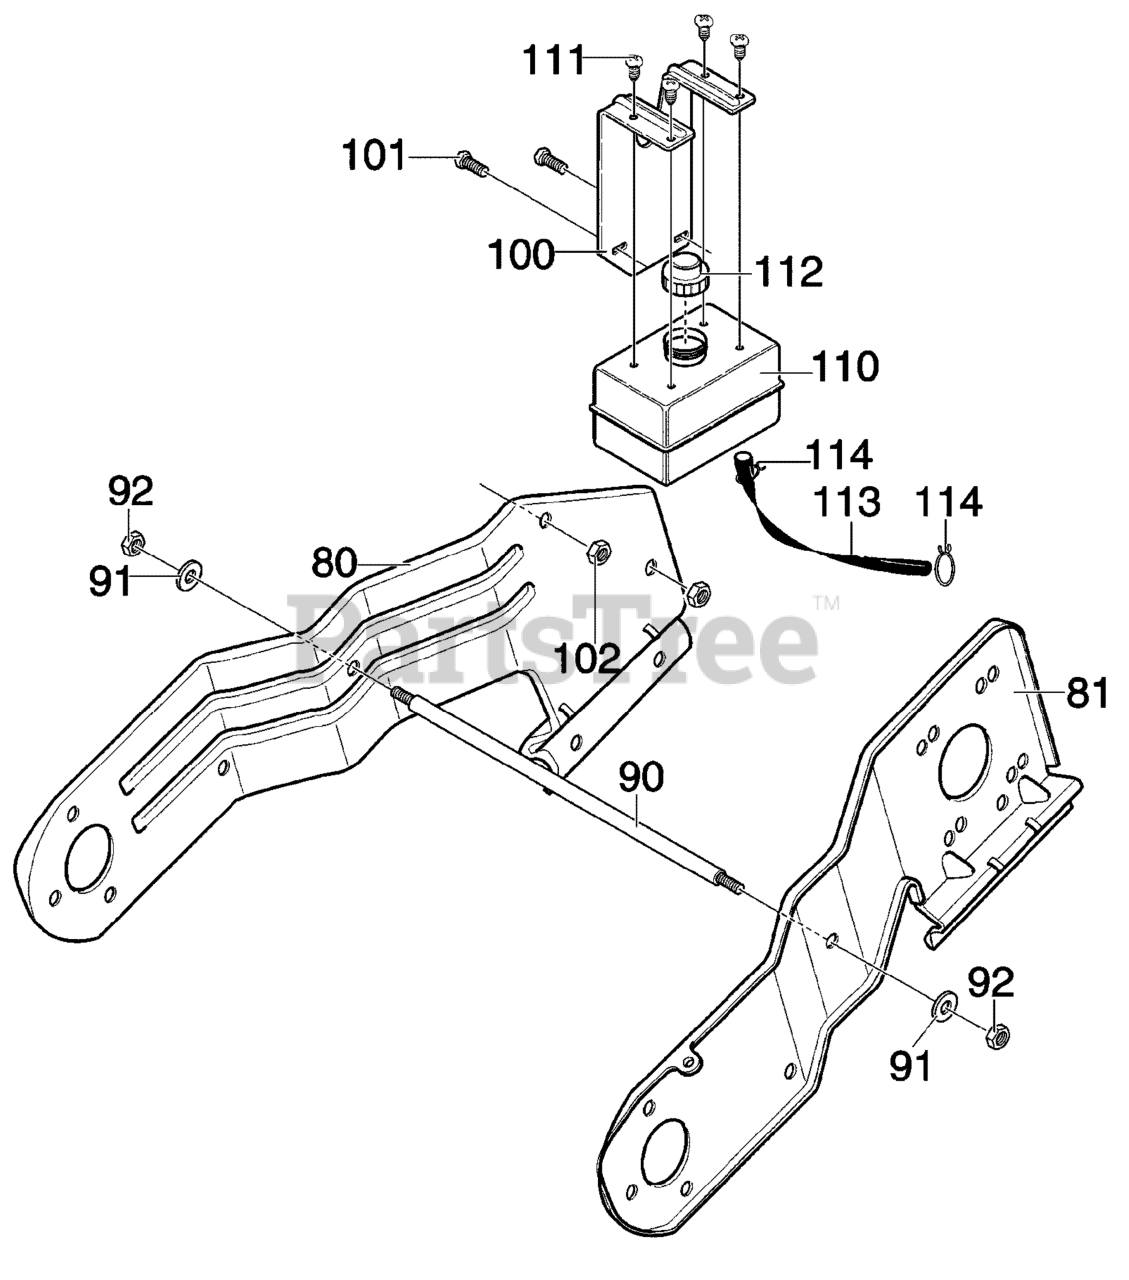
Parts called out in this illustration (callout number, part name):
80	FRAME SIDE SUPPORT RH
81	FRAME SIDE SUPPORT LH
90	ROD, SUPPORT
91	WASHER, HVSPTLK
92	NUT, 3/8-16 REGHEX
100	BRACKET, GAS TANK
101	SCREW, 1/4-20X.75
102	NUT, 1/4-20 YZ
110	TANK, FUEL
111	SCREW, 1/4-14X.88 WAHHTAP
112	CAP, GAS-BLACK
113	TUBING 11.50 IN.
114	CLAMP, FUEL LINE
